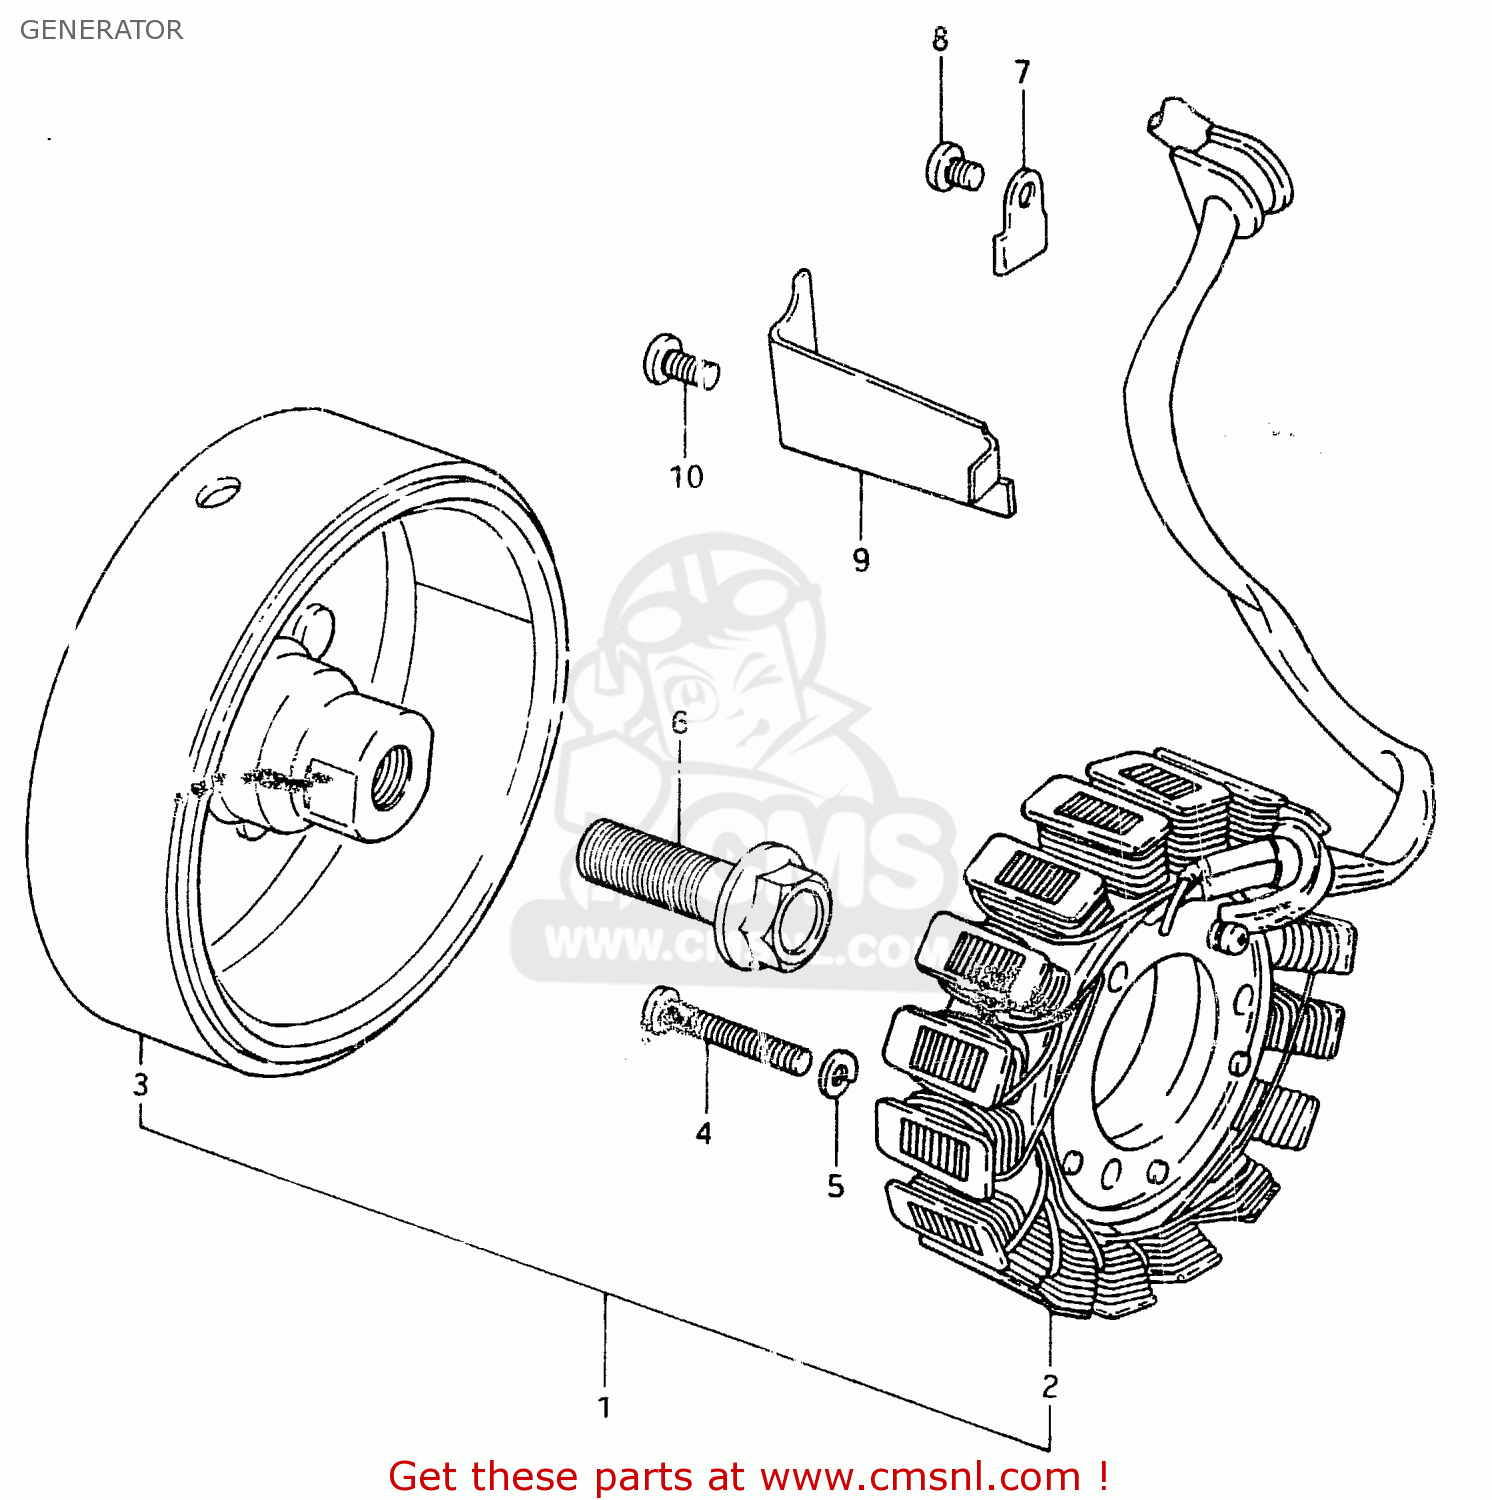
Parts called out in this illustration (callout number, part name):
1	GENERATOR ASSY
2	STARTER ASSY
3	ROTOR ASSEMBLY
4	SCREW
5	LOCK WASHER
6	BOLT(12X40)
7	CLAMP,GENERATOR LEAD WIRE
8	SCREW
9	CLAMP,GENERATOR LEAD WIRE
10	SCREW
